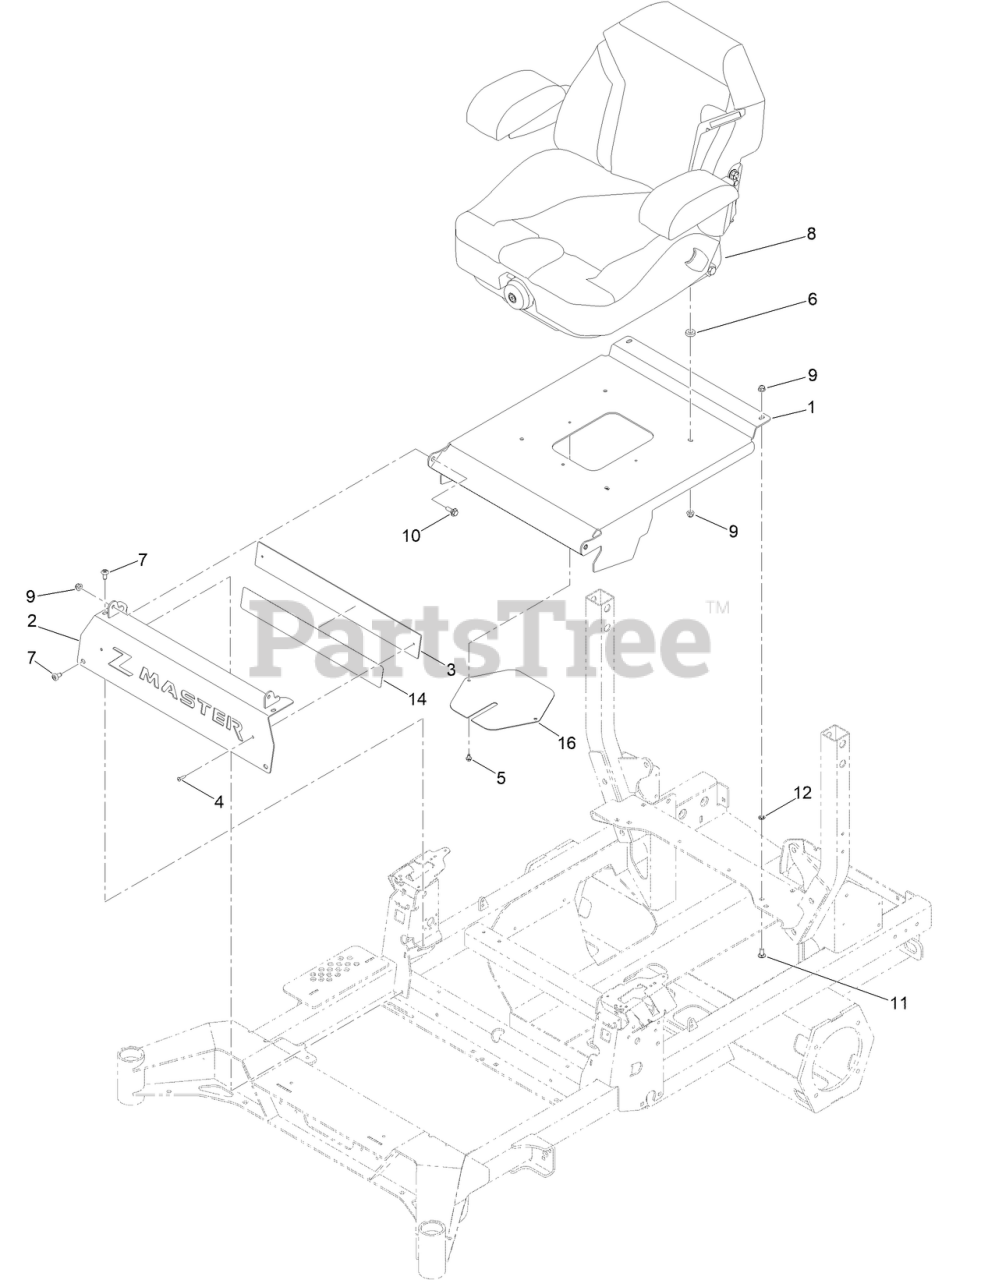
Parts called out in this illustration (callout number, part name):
1	PAN-SEAT
2	BADGE PLATE ASM
3	PLATE-BACKER
4	RIVET-TRIFOLD
5	SCREW-HWH
6	SPACER
8	SUSPENSION SEAT ASM
9	NUT-HF, NI
10	SCREW-SHOULDER
11	SCREW-CARR
12	NUT-PUSH
14	DECAL-BACKER PLATE
16	PLATE-COVER, SEAT
